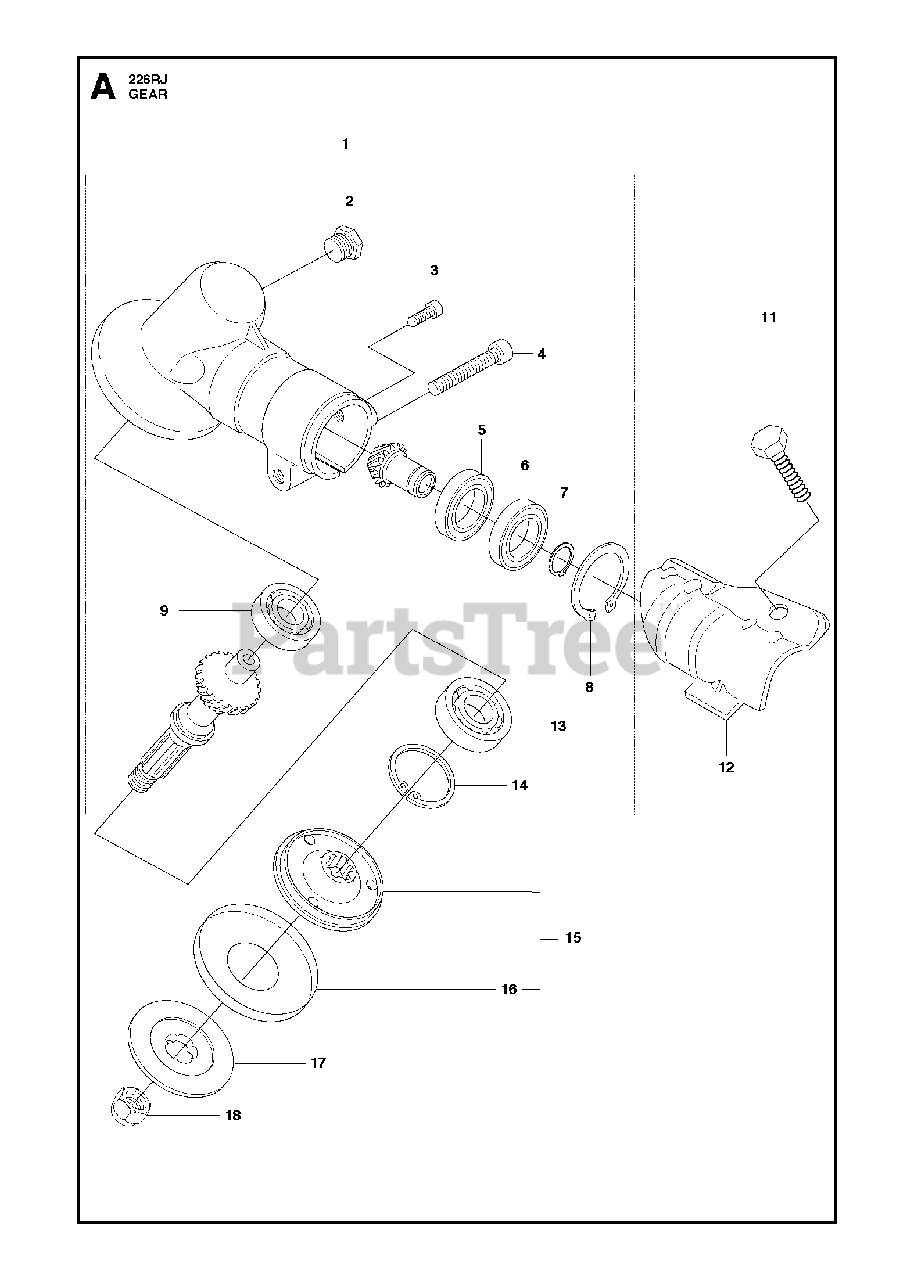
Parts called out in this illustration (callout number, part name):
1	GEARCASE-A
2	PLUG
4	SCREW
5	BALL BEARING 24X9X1/609ZR
7	RETAINING RING
8	RETAINING RING
9	BALL BEARING 8X22X7/608Z
11	SCREW
12	RP BRACKET TRIMMER GUARD
13	BALL BEARING
14	RETAINING RING SGH 28
15	DRIVE DISC
16	WASHER
17	SUPPORT FLANGE
18	GEARHEAD NUT - BRUSHCUTTER
